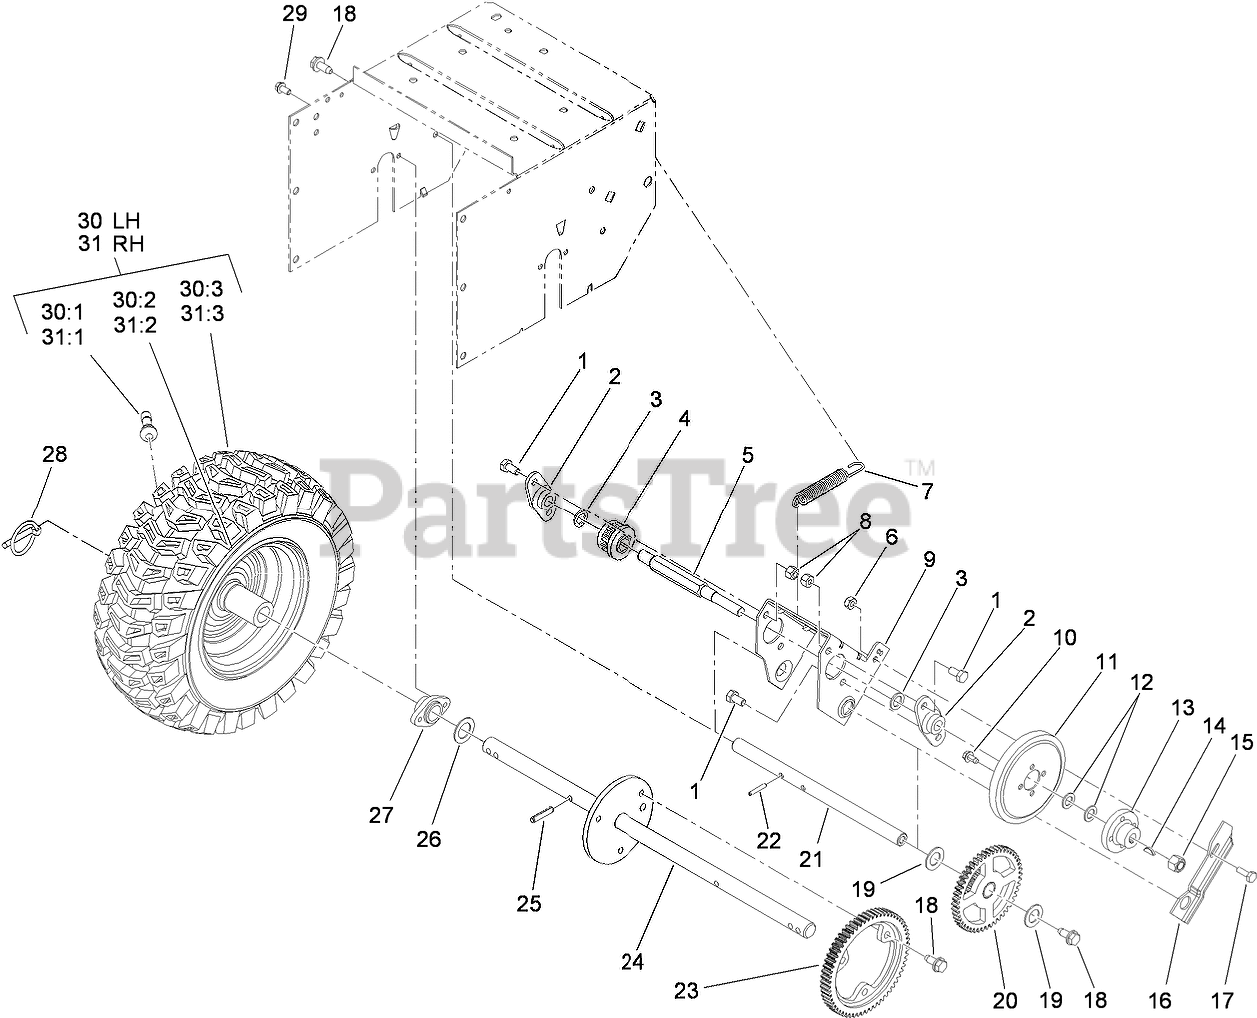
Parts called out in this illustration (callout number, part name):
1	SCREW-HH
2	BEARING-WHEEL, FRICTION
3	WASHER-FLAT
4	PINION
5	SHAFT-WHEEL, FRICTION
6	NUT-LOCK, NI
7	SPRING-TRACTION
8	NUT-LOCK, NI
9	BRACKET-SLIDING
10	SCREW-HWH
11	WHEEL-FRICTION
12	WASHER-THRUST
13	HUB-WHEEL, FRICTION
14	KEY-WOODRUFF
15	NUT-LOCK, NI
16	CAM-RECEIVER
17	SCREW-HH
18	SCREW-HWHTF
19	WASHER-SPECIAL
20	INTERNAL GEAR AND BUSHING ASM
21	SHAFT-PIVOT
22	PIN-SPRING
23	GEAR-AXLE
24	SHAFT-AXLE
25	PIN-ROLL, SLOTTED
26	WASHER-THRUST
27	BEARING-AXLE
28	PIN-LYNCH
29	SCREW-HWH
30	LH WHEEL AND TIRE ASM
30:1	STEM-VALVE
30:2	RIM-WHEEL
31	RH WHEEL AND TIRE ASM
31:1	STEM-VALVE
31:2	RIM-WHEEL
